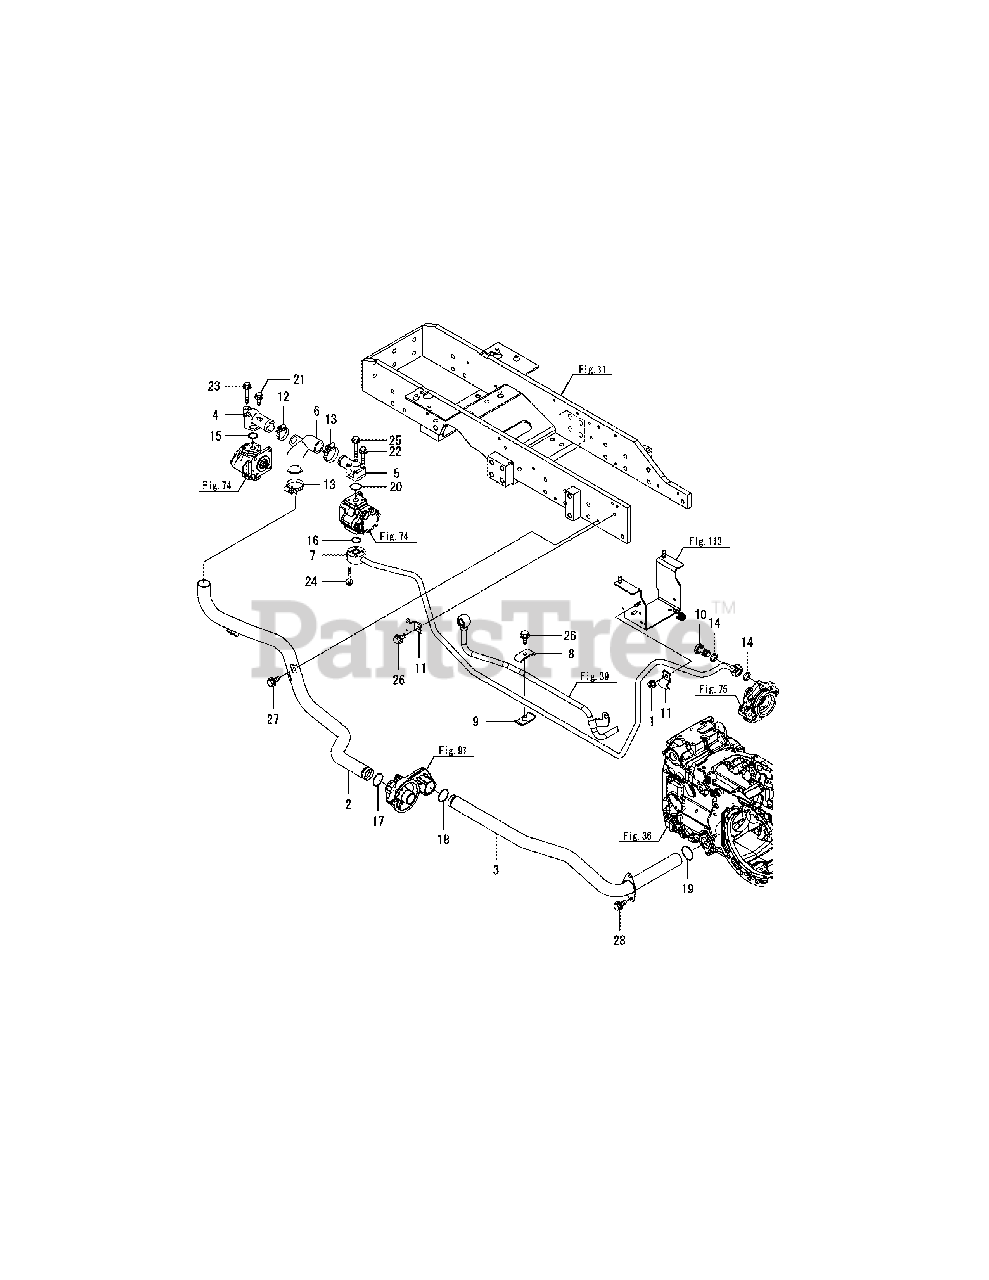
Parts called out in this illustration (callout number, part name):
1	NUT W/WASHER 8
2	LP PIPE, FRONT
6	HOSE, RUBBER LP P
10	CONNECTOR BOLT ASSY
15	O-RING 1A P-20.0
16	O-RING 1A P-22.0
17	O-RING 1A P-32.0
18	O-RING 1A P-32.0
19	O-RING 1A P-36.0
20	O-RING 1A S-25.0
21	BOLT M 6X 20 PLATED
22	BOLT M 6X 35 PLATED
23	BOLT M 6X 40 PLATED
24	BOLT M 6X 40 PLATED
25	BOLT M 6X 45 PLATED
26	BOLT M 8X 16 PLATED
27	BOLT M 8X 16 PLATED
28	BOLT M 8X 16 PLATED
